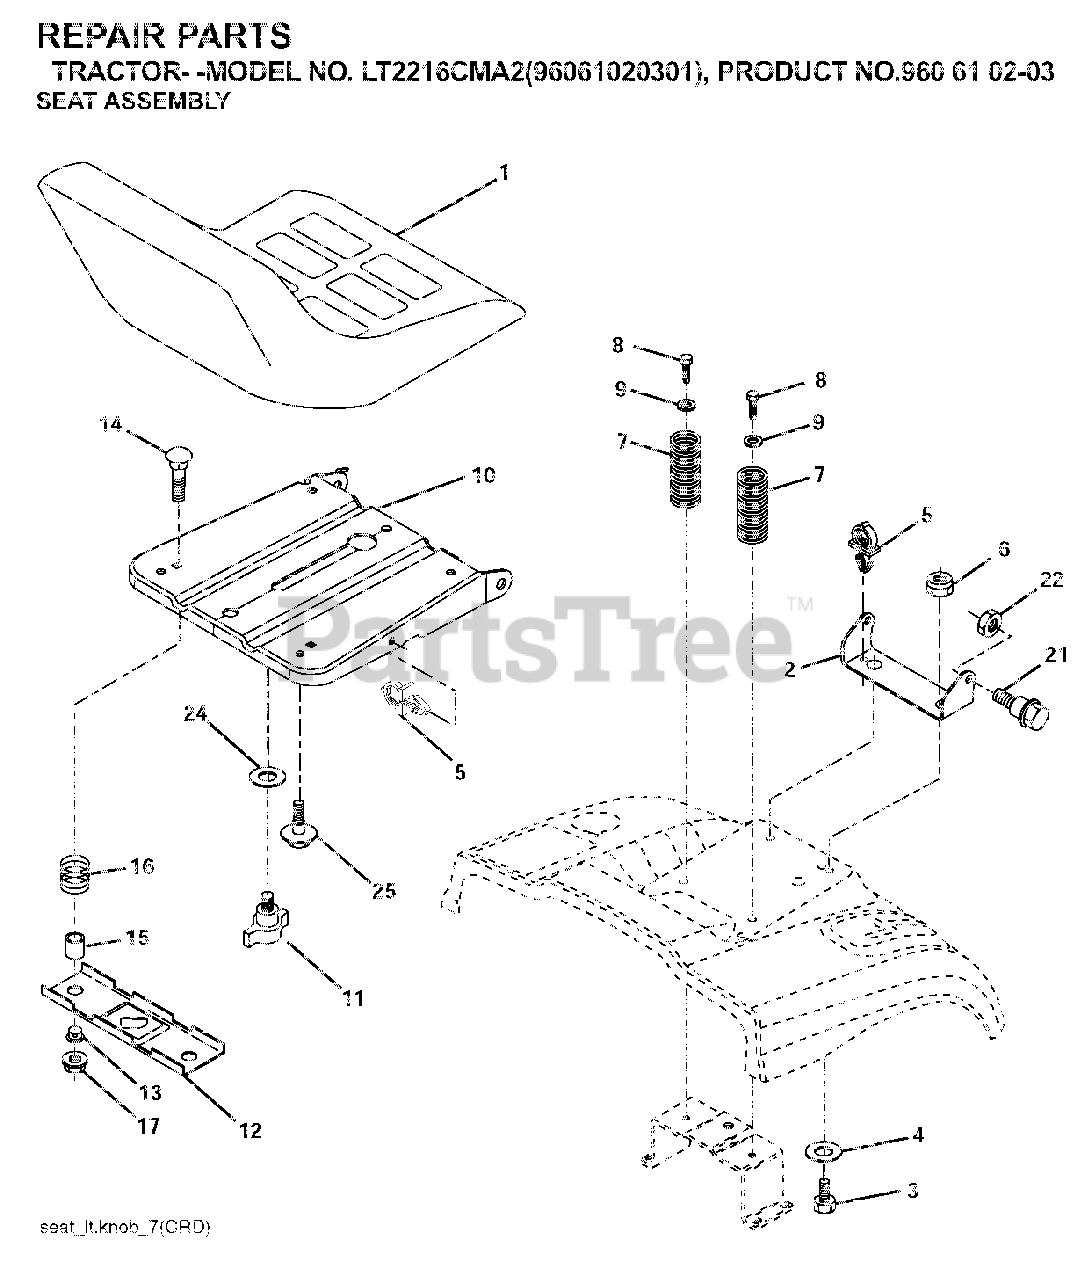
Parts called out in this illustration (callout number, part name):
1	SEAT.XG150.BLK.KB/SLD.NO-LOGO
2	SEAT PIVOT BRKT
4	WASHER PM
5	PUSH CLIP
6	NUT
7	SPRING COMPRESSION
8	SCREW 3/8-16X1
9	WASHER
10	PAN.ASM.SEAT.1SLOT
11	KNOB.SEAT.ADJ.WINGNUT
12	BRKT.MNTNG.SWITCH.SEAT
14	BOLT.ROUND.HEAD.SQUARE.NECK
15	SPACER SPLIT
16	SPRING COMPRESSED
17	NUT T
21	BOLT.SHOULDER.5/16-18
22	NUT.71038.31-18.HEX.NYLOCK
25	BOLT,SHOULD
